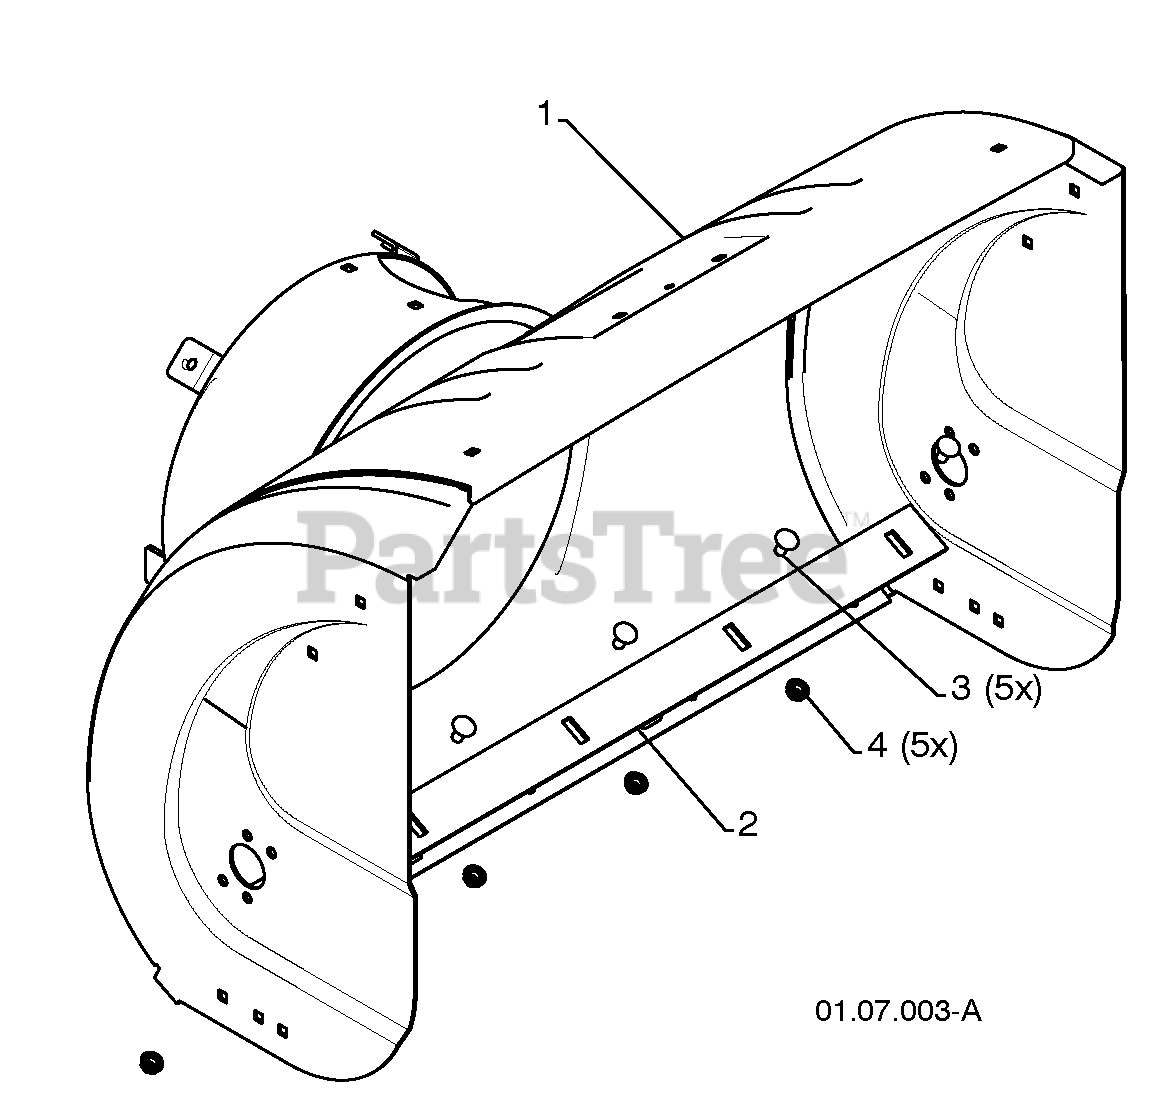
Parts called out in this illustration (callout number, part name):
1	AUGER HOUSING
2	SCRAPPER BAR
3	CARRIAGE BOLT 5/16-18 X .625
4	NUT 5/16-18
